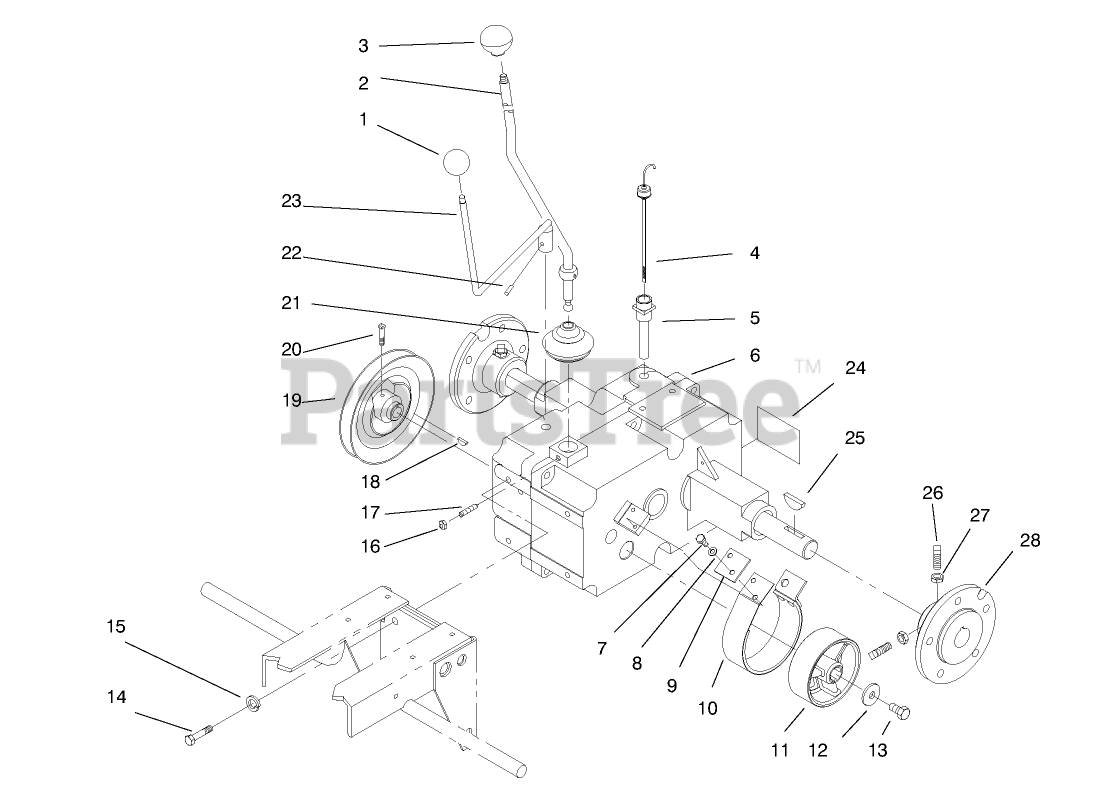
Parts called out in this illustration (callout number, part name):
4	DIPSTICK
6	TRANSMISSION ASM
7	SCREW-HH
8	WASHER-LOCK
10	BRAKE BAND ASM
11	DRUM-BRAKE
12	WASHER
13	SCREW-HEX HD CAP
14	SCREW-HH
15	WASHER-LOCK
16	NUT-HEX
17	SETSCREW
19	PULLEY-TRANSMISSION
20	SCREW-SQH
21	COVER-DUST
22	PIN-SPIROL
23	SHIFT ROD ASM
24	DECAL-UNIDRIVE
25	KEY-WOODRUFF
26	SCREW-SET, SQH
27	NUT-JAM
28	HUB-WHEEL
